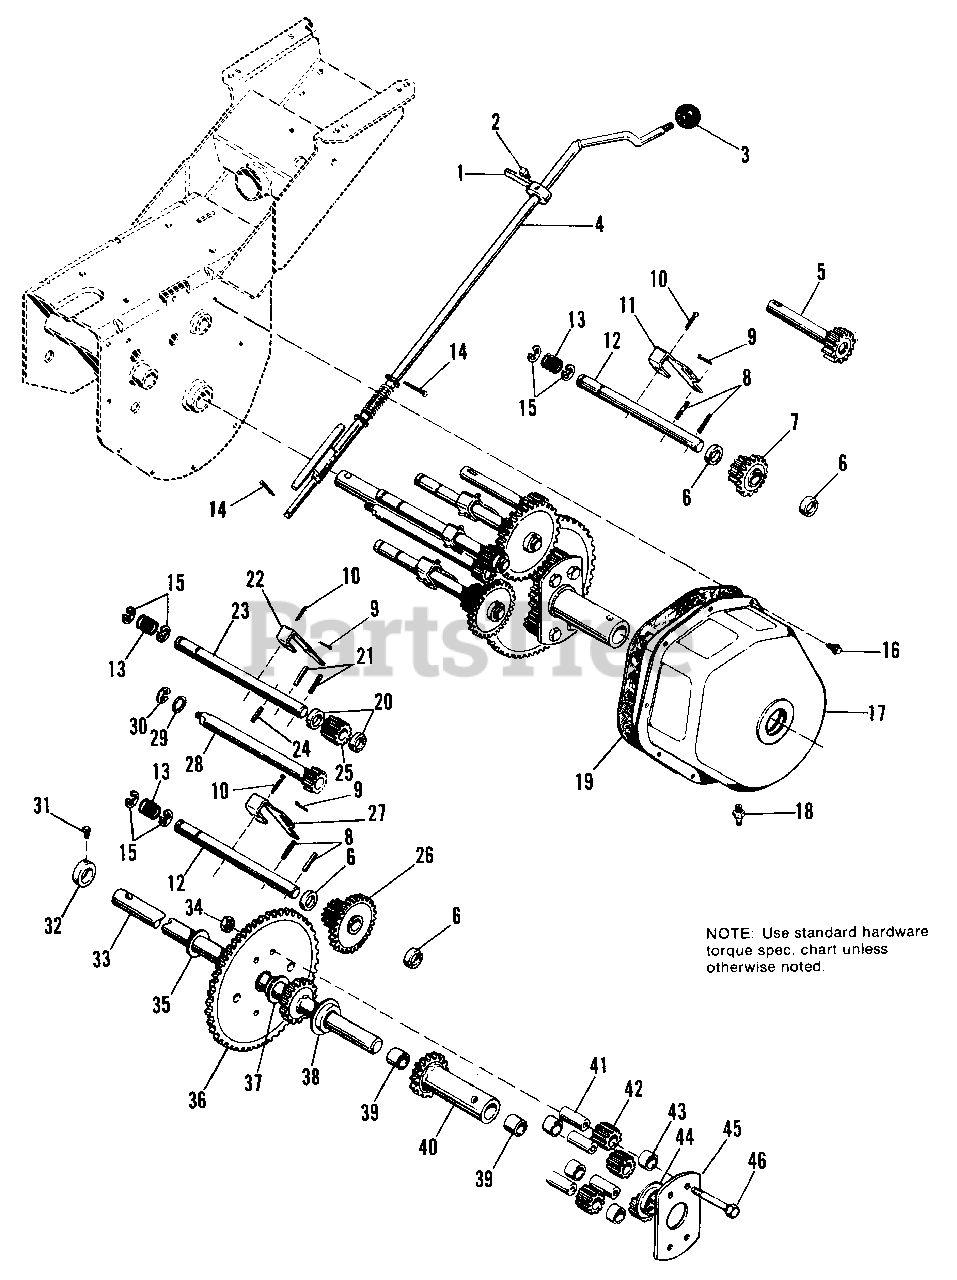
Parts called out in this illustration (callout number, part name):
1	LEVER ASSY.
2	SETSCREW, 5/16-18 x 1/2
4	ROD ASSY., Shift
5	SHAFT & GEAR ASSY.
6	COLLAR, Thrust
7	GEAR & BEARING ASSY.
8	PIN, Spring, 1/8 x 1
9	PIN, Cotter, 3/32 x 3/4
10	PIN, Cotter, 3/16 x 1-1/4
11	LINK, Shift, Hi
12	SHAFT, Intermediate
14	PIN, Cotter, 1/8 x 1
15	RING, Retaining
16	SCREW, Hex, Washer Hd., Taptite, 1/4-20 x 3/8
17	CASE ASSY., Gear
18	FITTING, Grease
19	GASKET, Gear Case
20	COLLAR, Thrust
21	PIN, Spring, 1/4 x 3/4
22	LINK, Shift, Reverse
23	SHAFT, Reverse
24	PIN, Spring, 5/32 x 1
25	PINION, Reverse
26	GEAR & BEARING ASSY.
27	LINK, Shift, Lo
28	SHAFT & GEAR ASSY.
30	RING, Retaining
31	SETSCREW, 5/16-18 x 3/8
32	COLLAR, Set
33	AXLE ASSY., L.H.
34	LOCKNUT, Hex, 3/8-16
35	WASHER, Special
36	GEAR, Drive
38	CUP, Thrust
40	AXLE & BUSHING ASSY.
42	PINION, Diff.
43	SPACER. Diff.
45	PLATE, Diff
46	CAPSCREW, Hex Hd., 3/8-16 x 2-1/2
